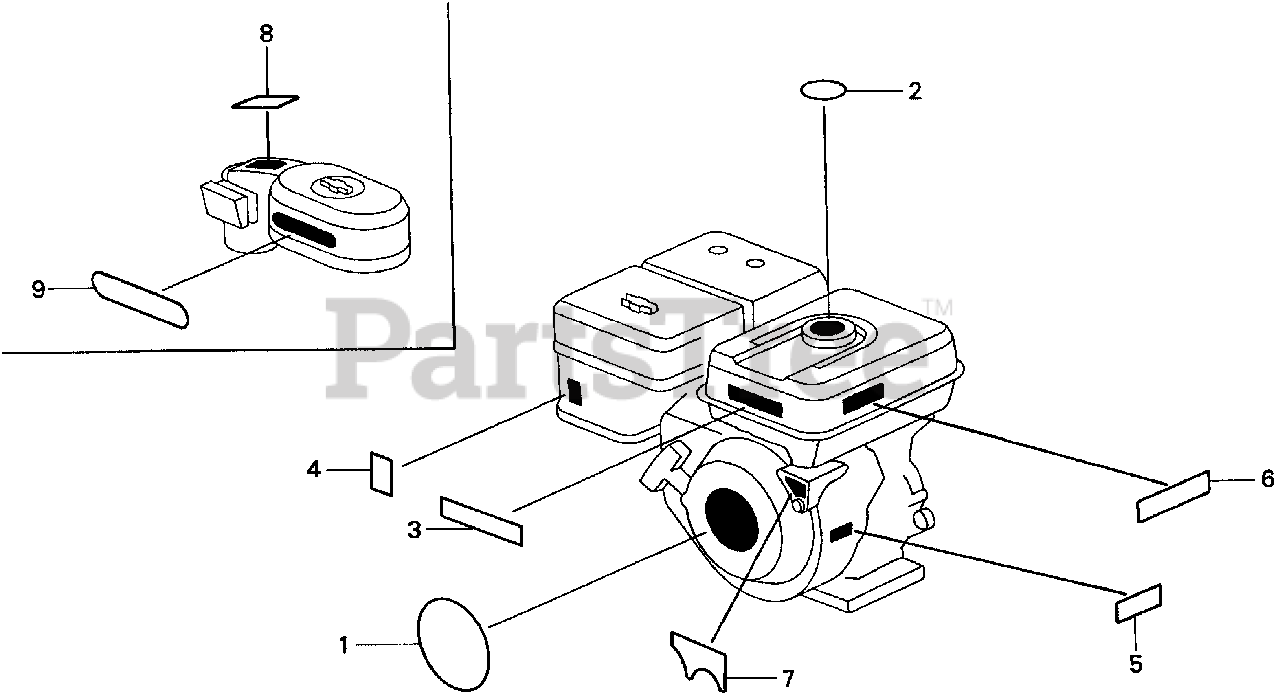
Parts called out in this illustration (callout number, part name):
1	EMBLEM
2	MARK, CAUTION (EXTERNAL)
3	LABEL, CAUTION
4	MARK, CHOKE (EXTERNAL)
5	LABEL, SPECIFICATION
6	MARK, OIL ALERT (GERMAN)
6	MARK, OIL ALERT (FRENCH)
6	MARK, OIL ALERT (E)
7	MARK, OIL ALERT (EXTERNAL)
8	LABEL, AIR CLEANER CAUTION
9	MARK, AIR CLEANER SALES POINT
10	LABEL (E-SPEC)
